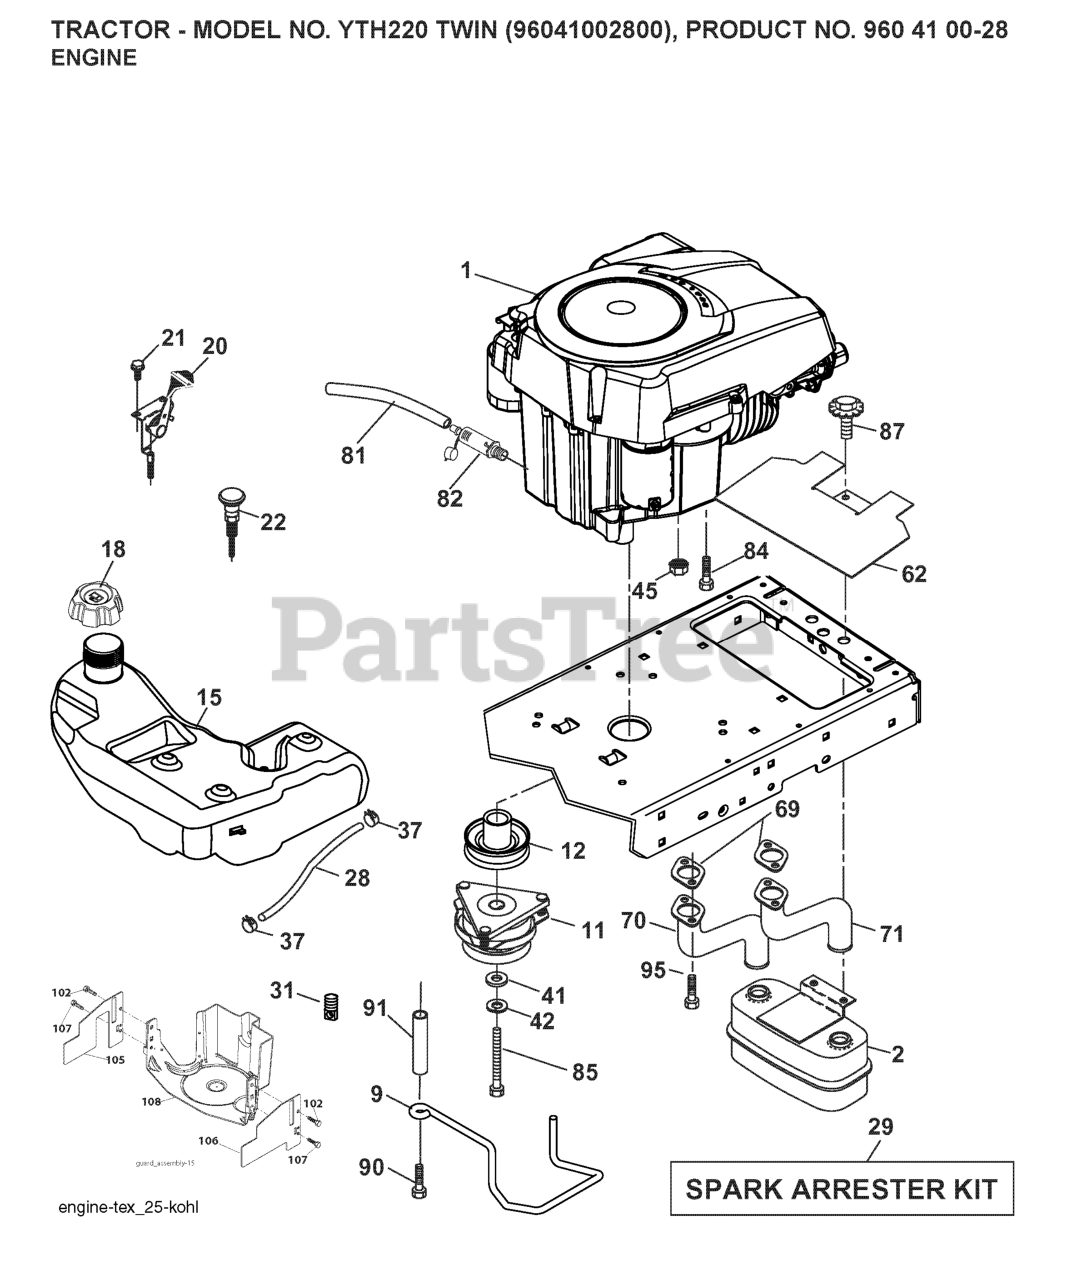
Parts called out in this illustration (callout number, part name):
2	MUFFLER.TWIN.CYL.LOW.TONE
9	KEEPER.BELT.ENGINE.3.25 (3 2)
11	CLUTCH MZ ZTR GT.48/54"1.125"
12	PULLEY.ASM.ENGINE.1-1/8X3-1/4
15	TANK.FUEL.4GAL
18	CAP.FUEL.TANK.3"GREY
20	THROTTLE CONTROL
21	SCREW
22	CONTROL.CHOKE.ERGO.PUSH-IN.BLA
28	REPL BY 532 00 85-43
29	KIT.SPARK ARRESTOR 794945 B&S
37	HOSE CLAMP
42	LOCKWASHER
45	NUT
62	RP SHIELD HEAT MUFFLER
70	RP.PIPE-EXHAUST LH
71	RP.PIPE-EXHAUST RH
81	TUBE, DRAIN OIL ASM.
82	PLUG DRAIN OIL EASY
84	SCREW 3/8-16X1
85	BOLT HEX 7/16-20 X 3.75 GR. 5
87	BOLT.5/16-18UNCX1.W/SEMS.BLK
90	SCREW 3/8-16X1
91	BUSHING.1.375OD
95	SCREW.SOCKET HD.5/16-1
102	SCREW
105	SHIELD SIDE
106	SHIELD SIDE
107	SCREW.1/4-20X5/8
